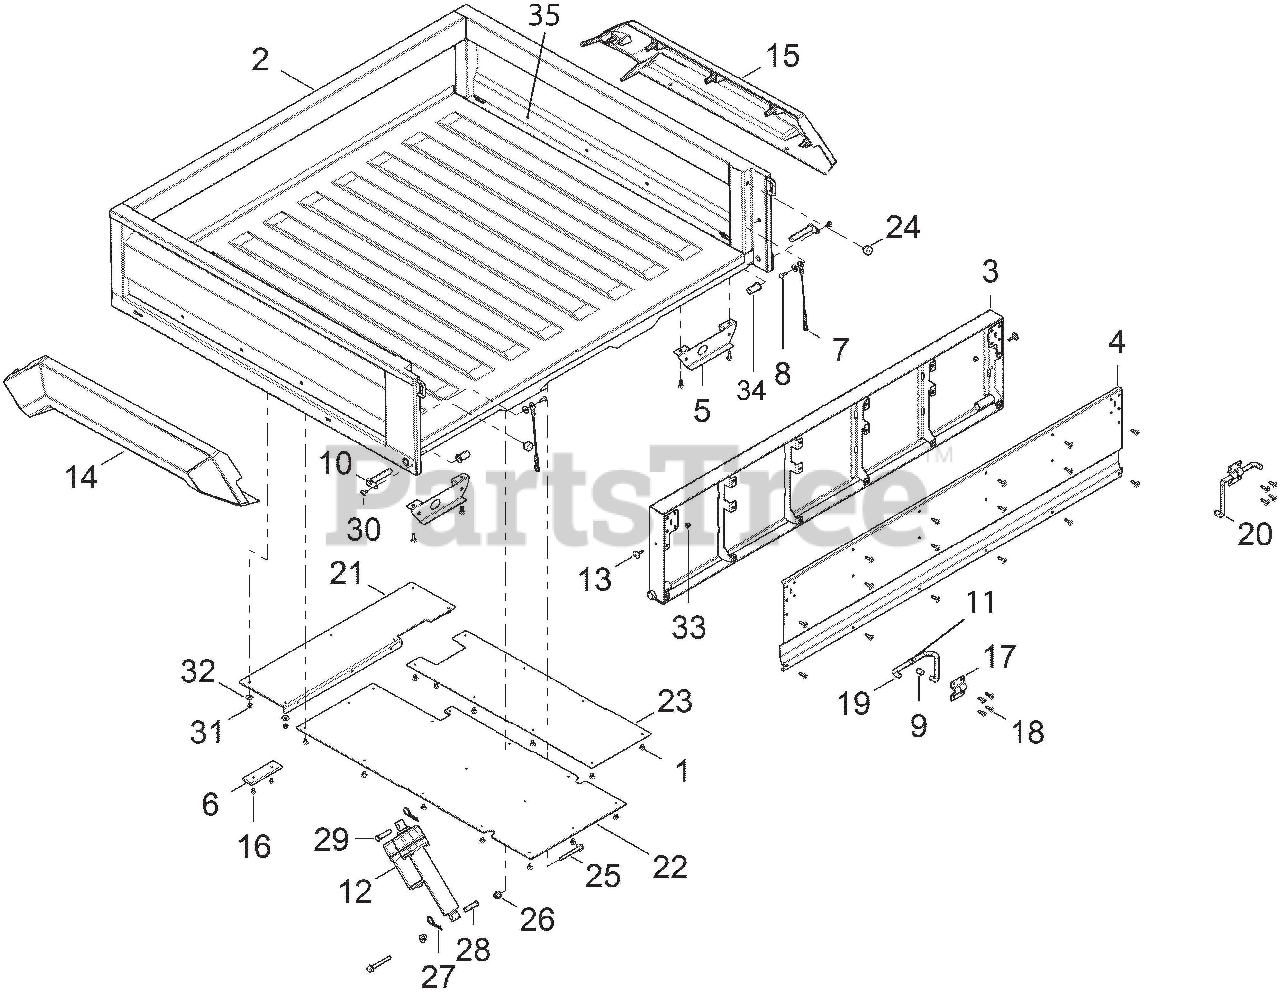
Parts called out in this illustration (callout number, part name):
1	RIVET(50) *
2	BOX-ARIENS,GRAVELY RED
3	TAILGATE,ARIENS,GRAVELY RED
4	PANEL, TAILGATE, GRAVELY RED
5	BRKT-TAIL LIGHT MOUNT
6	SHIELD, HEAT EXHAUST MID
7	CABLE, TAILGATE
8	BLT-SHLDR .188X.188X.25-20
9	CAP, TAILGATE LATCH
10	PIN-TAILGATE MOUNT
11	BUSHING, TAILGATE LATCH
12	ACTUATOR-BOX LIFT,SPLY
13	SCR-TXTH-M6X1.0X25 RIE,SHDR
14	FLARE-BOX,LH,ARIENS
15	FLARE-BOX,RH,ARIENS
16	NUT-M6 FLANGE,NYLOK
17	BRKT-TAILGATE LATCH
18	SCR-TXTH-M6X1.0X25 RIE
19	ROD, LATCH, LH
20	ROD, LATCH, RH
21	SHIELD, HEAT, EXHAUST, FRONT
22	SHIELD, HEAT, EXHAUST, REAR
23	SHIELD, HEAT EXHAUST MID
24	BUMPER, TAILGATE
25	SCR-HXFL-M10X1.25X80 8.8 ZOD
26	NUT-M10X1.25,FLG,NYLOC-OLIVE D
27	CLIP, HITCH PIN
28	PIN, CLEVIS
29	PIN, CLEVIS BOX LIFT 2"
30	SCR-M6X1X16 TR/TX-M
31	NUT-M6 FLANGE,NYLOK
33	NUT-M6 FLANGE,NYLOK
34	BUSHING, TAILGATE PIVOT PIN
35	SCR-TXPH-#14 X .75 HI-LO RIE
